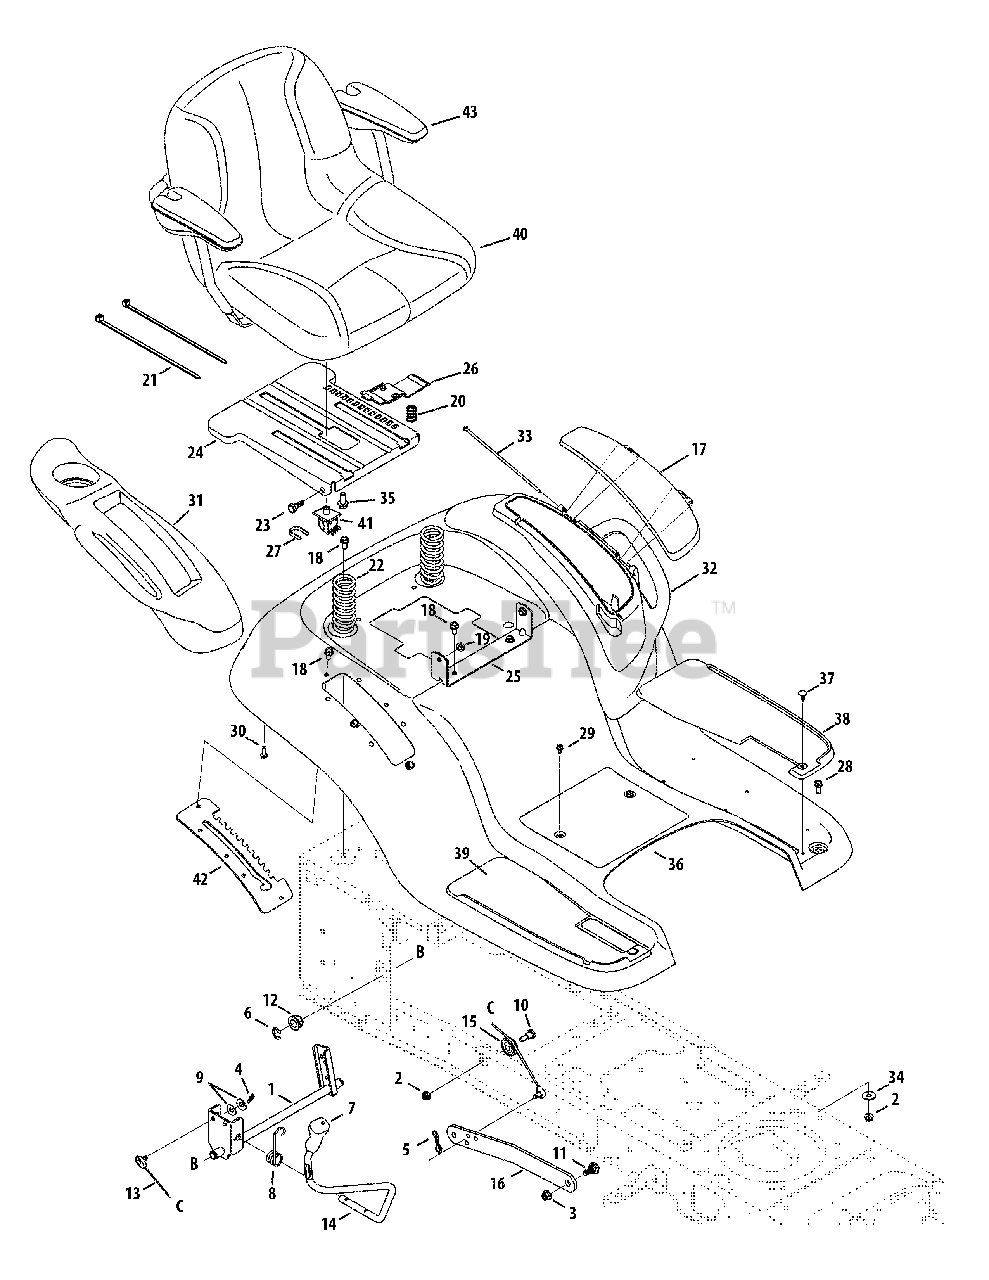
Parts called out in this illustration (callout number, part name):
1	Shaft Ass’y, Lift, 50"
1	Shaft Ass’y, Lift, 54"
2	Nut, Flange Lock, 5/16-18, Grf
3	Nut, Flange Lock, 3/8-16, Grf
4	Pin, Cotter, .072 Dia. x 1.13
5	Pin, Cotter, Bow-Tie 72
6	Ring, E Type, .625 Dia. Shaft
7	Grip, Handle, Cub, .50 ID
8	Spring, Torsion
9	Washer, Spring, .401 x .870 x .063
10	Screw, Shoulder, .437 x .470, 5/16-18
11	Bolt, Shoulder, .50, 3/8-16
12	Bearing, Hex Flange
13	Cable, Lift, 16.16
14	Handle, Lift,
15	Pulley, Roller, Cable
17	Door, Cover, Fender
18	Screw, Self-tapping, 5/16-18, .750,
19	Nut, Flange Lock, 5/16-18, Gr5, Sd Lk
20	Spring, Compression, .68 x 1.065 x .055
21	Cable, Tie, 3/16 x .05 x 7.4
22	Spring, Comprs, 1.71 x 3.735 x .238
23	Screw, Shoulder, .437 x .268, 5/16-18
24	Bracket, Mounting, Seat
25	Bracket, Pivot, Seat
26	Lever, Seat Adjustment
27	Clip, Retaining, Switch
28	Hex Screw, 5/16-18, .75, Gr5, Std
29	Screw, Self-tapping, 1/4-20, 0.500,
30	Screw, HL, 1/4-15, 0.750,
31	Cover, Fender, RH
32	Cover, Fender, LH
34	Washer, Flat .344 x 1.00 x .063
35	Hex Flange Screw, 3/8/16, .875, Gr5
36	Fender, Cub Hydro
37	Clip, Ratchet, .250 Dia
38	Pad, Foot, LH
39	Pad, Foot, RH
40	Seat, High Back Cloth w/o Arm Rest
41	Switch, Seat
42	Bracket, Lift
43	Arm Rest Kit
